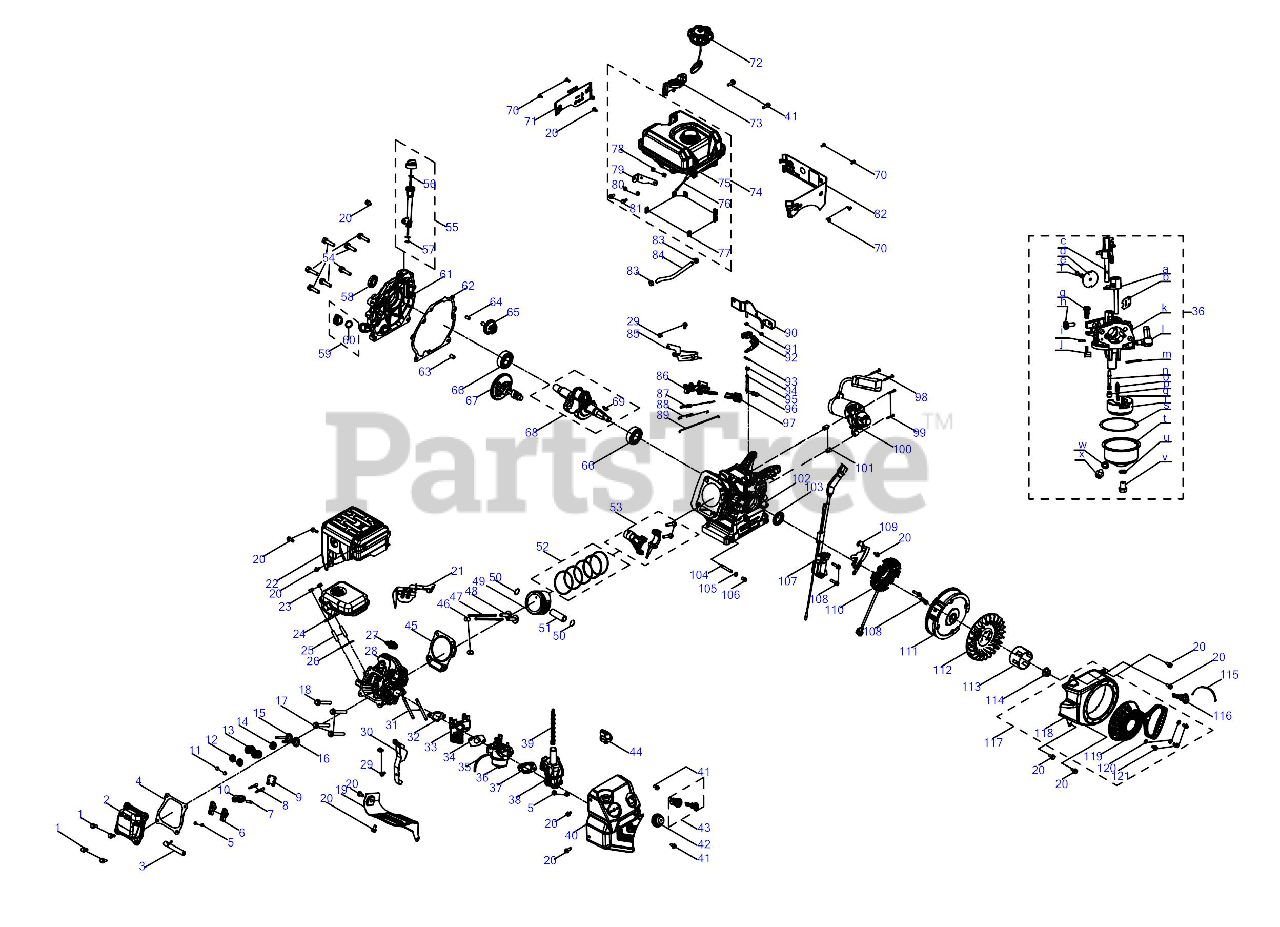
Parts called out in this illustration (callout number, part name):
1	BOLT M6-1 x 16 GR8.8
2	VALVE COVER
3	BREATHER HOSE
4	VALVE COVER GASKET
6	Rocker Arm Assembly
7	Rocker Arm Shaft
8	BOLT M6-1 x M8-1.25 x 50MM
9	PUSH ROD GUIDE
10	ROCKER ARM PIVOT BLOCK
11	EXHAUST VALVE ADJUSTER
12	EXHAUST VALVE SPRING RETAINER
13	VALVE SPRING
14	INTAKE VALVE SEAL
15	EXHAUST VALVE
16	INTAKE VALVE
17	SCREW M10-1.25 x 65 x GR10.9
18	BOLT M10-1.25 x 70
19	AIR SHIELD
20	BOLT M6-1 x 12 GR8.8
21	Shroud
22	MUFFLER GUARD
25	STUD M8-1.25 x 34
26	MUFFLER GASKET
27	SPARK PLUG
28	Cylinder Head
29	BOLT M6-1 x 12 GR8.8
30	SNOW GUARD
31	STUD M6 X 90
32	CARBURETOR INSULATOR GASKET
34	CARBURETOR GASKET
35	PRIMER HOSE
36	Carburetor
37	CARBURETOR GASKET PLATE
38	HEATER BOX
39	CHOKE LINKAGE
40	CONTROL PANEL
41	BOLT M6-1 x 18 GR8.8
43	ENGINE KEY SWITCH ASSEMBLY
44	CHOKE LEVER
45	CYLINDER GASKET
46	Pin, 12?16
47	PUSH ROD (SINGLE)
50	PISTON PIN SNAP
51	PISTON PIN
52	PISTON RING SET
53	CONNECTING ROD
54	BOLT M8-1.25 x 32 GR5.8
55	Dipstick
56	DIPSTICK O-RING
57	OIL FILL TUBE O-RING
58	OIL SEAL
60	O-RING 15.8 x 2
61	CRANKCASE COVER
62	CRANKCASE COVER
63	DOWEL PIN
64	DOWEL PIN
65	GOVERNOR GEAR/SHAFT ASSEMBLY
66	BALL BEARING
68	CRANKSHAFT ASSEMBLY
69	FLYWHEEL KEY
70	BOLT: M5 x 14
71	DECORATIVE SHEET: RIGHT
73	DECORATIVE COVER
76	FUEL FILTER
77	FUEL TANK MOUNT THREADED TAB
79	FUEL TANK MOUNT TAB
80	WASHER 6.5 X 1.5 X 12
81	BOLT M6 X 20
82	DECORATIVE SHEET: LEFT
83	HOSE CLAMP
84	FUEL HOSE 6.3 X 12.5 X 162
85	GOVERNOR SHIELD
86	GOVERNOR GEAR BRACKET ASSEMBLY
87	GOVERNOR SPRING
88	THROTTLE SPRING
89	GOVERNOR ROD
90	FUEL TANK BRACKET
92	GOVERNOR LEVER
93	COTTER PIN
94	GOVERNOR SEAL
96	GOVERNOR SHAFT
97	THROTTLE KNOB
99	BOLT M6-1 x 32 GR8.8
100	ELECTRIC STARTER
101	DOWEL PIN
103	OIL SEAL
104	OIL DRAIN PIPE
105	WASHER
106	OIL DRAIN PLUG
107	IGNITION MODULE
108	BOLT M6-1 x 25 GR8.8
109	BLOWER SHIELD
111	FLYWHEEL
112	COOLING FAN
113	STARTER CUP
114	FLYWHEEL NUT
116	IGNITION KEY
117	Recoil Starter
118	BLOWER HOUSING
119	RECOIL STARTER ASSEMBLY
120	RECOIL FLAT WASHER
121	BOLT M6 x 10 GR8
